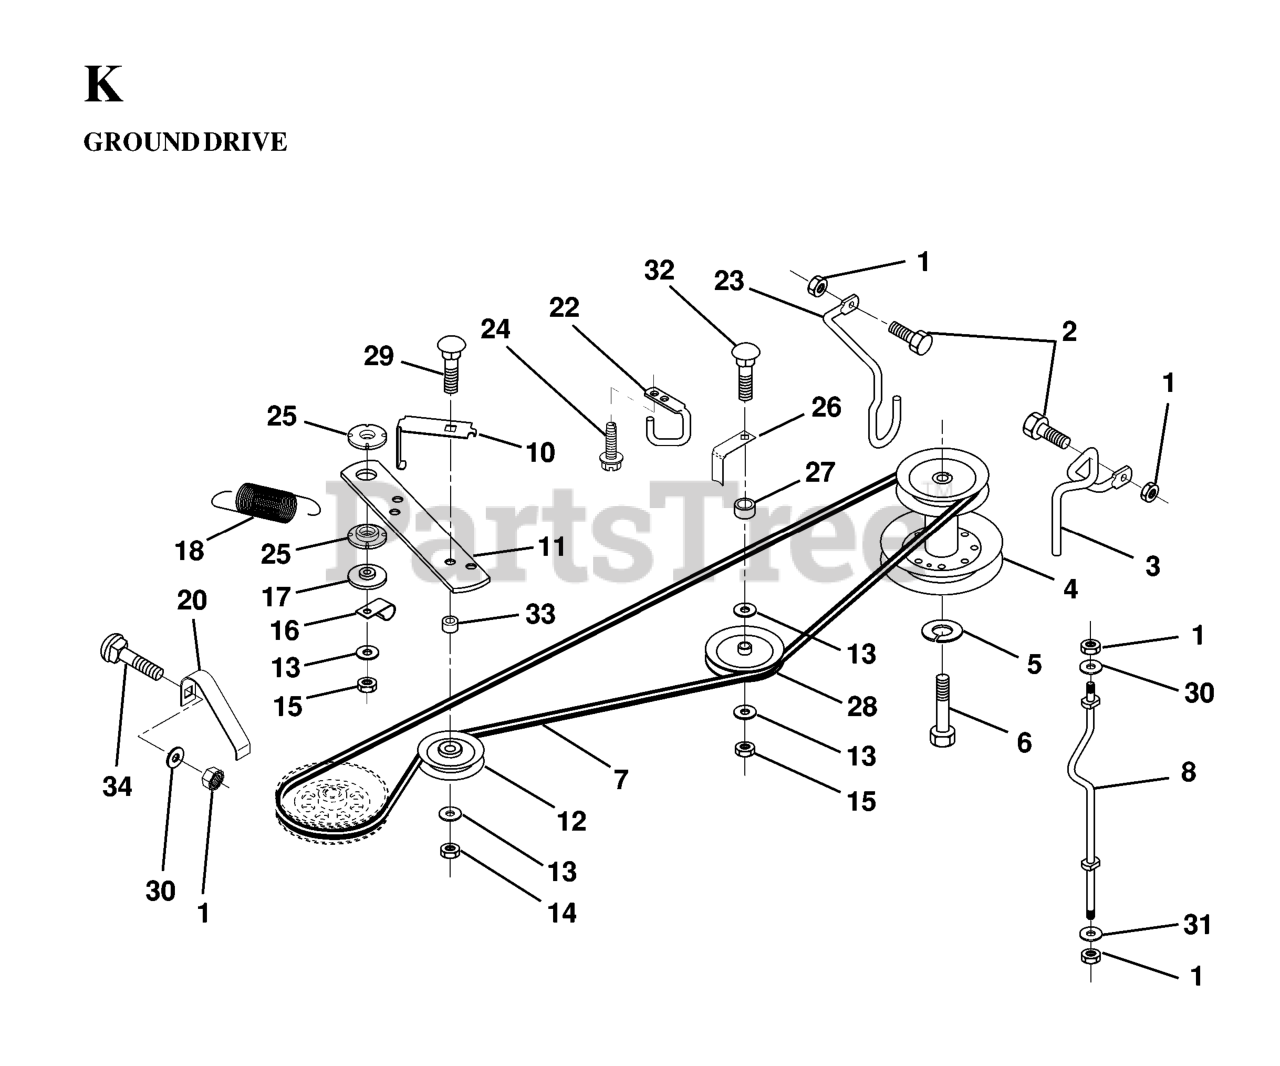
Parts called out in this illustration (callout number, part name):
1	NUT.71038.31-18.HEX.NYLOCK
2	BOLT
3	BELT GUIDE
4	PULLEY.ENGINE.36/38 LR
5	LOCKWASHER
6	Bolt, Hex Hd. 7/16-20 UNF Grade 5
10	KEEPER, BELT
11	ARM, GROUND DRIVE CLUTCH
12	PULLEY.IDLER.FLAT
13	WASHER
14	LOCKNUT
16	CLIP,INSULATOR
17	SPACER, RETAINER
18	SPRING.EXTENSION
20	KEEPER, BELT
22	KEEPER,FRA DR BEL
23	KEEPER-MOWER DRIVE LH
24	SCREW
25	BUSHING NYLON COLLERED
26	KEEPER, BELT
28	PULLEY.IDLER.V.
29	BOLT
30	WASHER
31	WASHER M
32	BOLT
33	SPACER NLA
34	RP BOLT 5/16-18 X3/4 ZN/YEL GR
